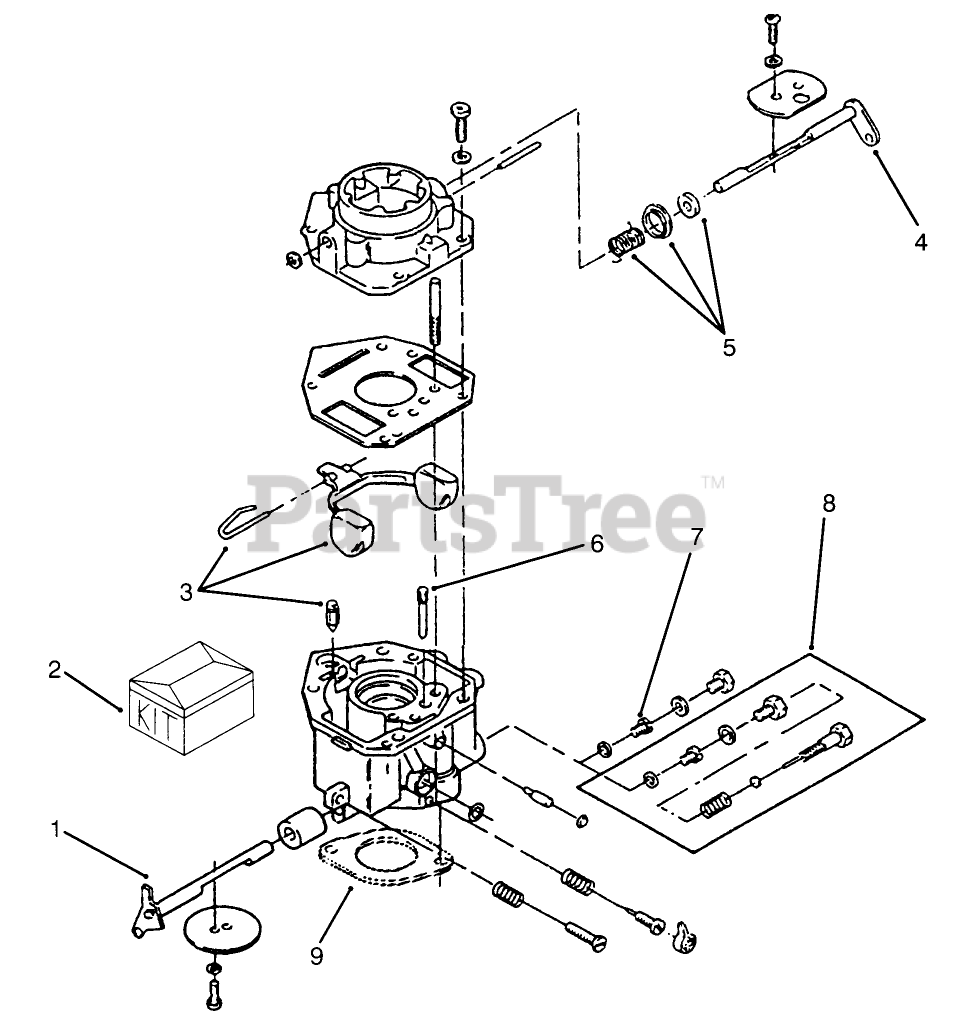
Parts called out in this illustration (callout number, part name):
2	REPAIR KIT
3	FLOAT
4	CHOKE KIT SHAFT
6	IDLE-JET
8	FIXED-JET
9	GASKET-CARBURETOR
